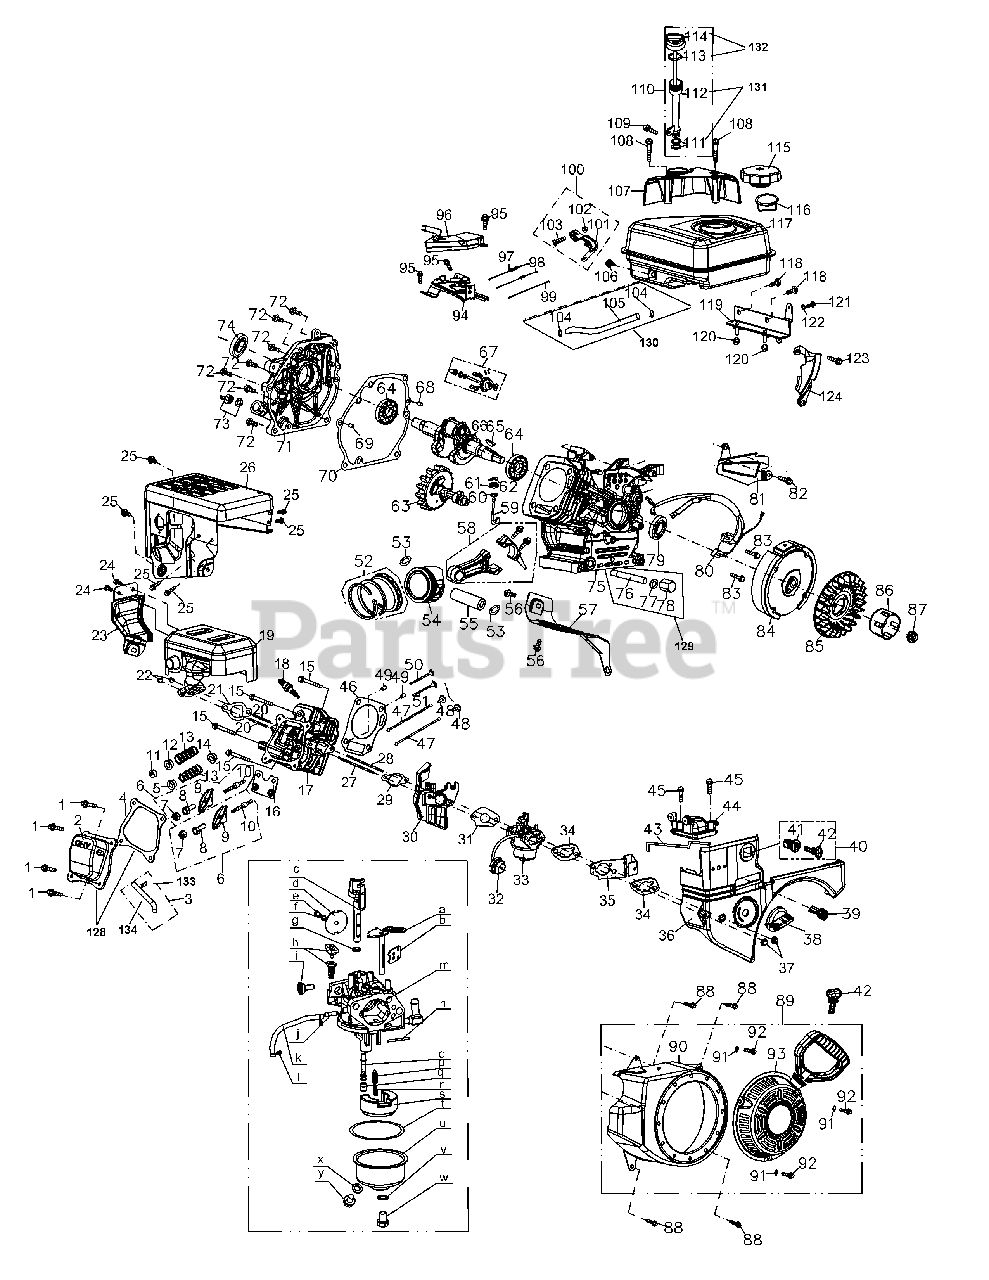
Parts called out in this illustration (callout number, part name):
1	Flange Bolt M6 X 16
2	Valve Cover
3	Breather Hose Assembly
4	Valve Cover Gasket
5	Intake Valve Spring Retainer
6	Rocker Arm Assembly
7	Nut - Pivot Locking
8	Nut - Valve Adjust
9	Rocker Arm
10	Bolt - Pivot
11	Exhaust Valve Adjuster
12	Exhaust Valve Spring Retainer
13	Valve Spring
14	Intake Valve Seal
15	Bolt - M8 X 55 Zin
16	Push Rod Guide
17	Cylinder Head Complete
18	Plug:Spark
19	Muffler Assembly
20	Muffler Stud Assembly
20	Muffler Stud
21	Muffler Gasket
23	Shield - Exhaust Pipe
24	Bolt - Flange M6 X
25	Bolt - M6 X 12 Zin
26	Muffler Shroud
27	Stud-Carb
28	Stud - M6 X 105
29	Gasket-Carb Insulator
30	Carburetor Insulator Plate
31	Carburetor Gasket
32	Primer Assembly
32	Primer Bulb Only
33	Carburetor Assembly
34	Carburetor Gasket Plate
35	Bracket - Choke Control
36	Shroud-Engine
38	Choke Knob
39	Throttle Knob
40	Ignition Switch Assembly
41	Ignition Switch
42	Key-Ignition Sw Snow
43	Push Rod-Choke
44	Air Filter Heating Pipe Cover
45	Bolt - Flange M6 X
46	Gasket-Cylinder Head
47	Kit-Push Rod
48	Tappet
49	Pin - Dowel
50	Valve Kit
51	Valve Kit
52	Piston Ring Set
53	Piston Pin Snap Ring
54	Piston
55	Piston Pin
56	Bolt - M6 X 12 Zin
57	Shield - Air
58	Connecting Rod Assembly
59	Governor Arm Shaft
60	Washer
61	Governor Seal
62	Clip-Governor Shaft
63	Camshaft Assembly
64	Bearing
65	Key:Flywheel
66	Crankshaft
67	Governor Gear/Shaft Assembly
68	Pin-Dowel
69	Dowl Pin 9X14
70	Crankcase Cover Gasket
71	Crankcase cover
72	Bolt
73	Oil Fill Plug Assembly
73	Oil Fill Plug O-Ring Only
74	Oil Seal
75	Crankcase
76	Oil Drain Pipe
77	Washer
78	Bolt - Drain Plug
79	Oil Seal
80	Ignition Coil
81	Shield - Air Flow
83	Bolt - Flange M6 X
84	Flywheel
85	Cooling Fan
86	Starter Cup
87	Nut - M14
88	Bolt
89	Blower Housing Assembly
90	Fan Cover-Complete
91	Flat Washer-Recoil
92	Flange Bolt M6 X 1
93	Recoil Starter Asm
94	Throttle Control Assembly
95	Bolt-M6 X 12
96	Shield - Governor
97	Governor Spring
98	Spring-Throttle Return
99	Rod-Governor
100	Governor Arm Assembly
101	Bracket - Governor Arm
102	Nut - M6
103	Bolt - M6 X 21 Gov
104	Fuel Hose Clamp
105	Fuel Line
106	Bolt
107	Engine/Dipstick Cover
109	Bolt
110	Dipstick Assembly Complete
111	O-Ring Fill Tube
112	Dipstick Tube
113	Dipstick-O Ring
114	Oil Cap
115	Fuel Cap Asm
116	Fuel Level Indicator
117	Tank:Fuel
118	Bolt - Flange M6 X
119	Bracket - Switch Housing Mount
120	Nut - M6
121	Bolt-M4 X 10
122	Washer
123	Bolt - Flange M6 X
124	Shield - Blower Housing
126	Fuel Tank Nipple
127	Starter Handle
128	Valve Cover Kit
129	Oil Drain Assembly
130	Fuel Line Kit
131	Oil Fill Tube Assembly
132	Dipstick Assembly
133	Hose Clamp
134	Breather Hose
